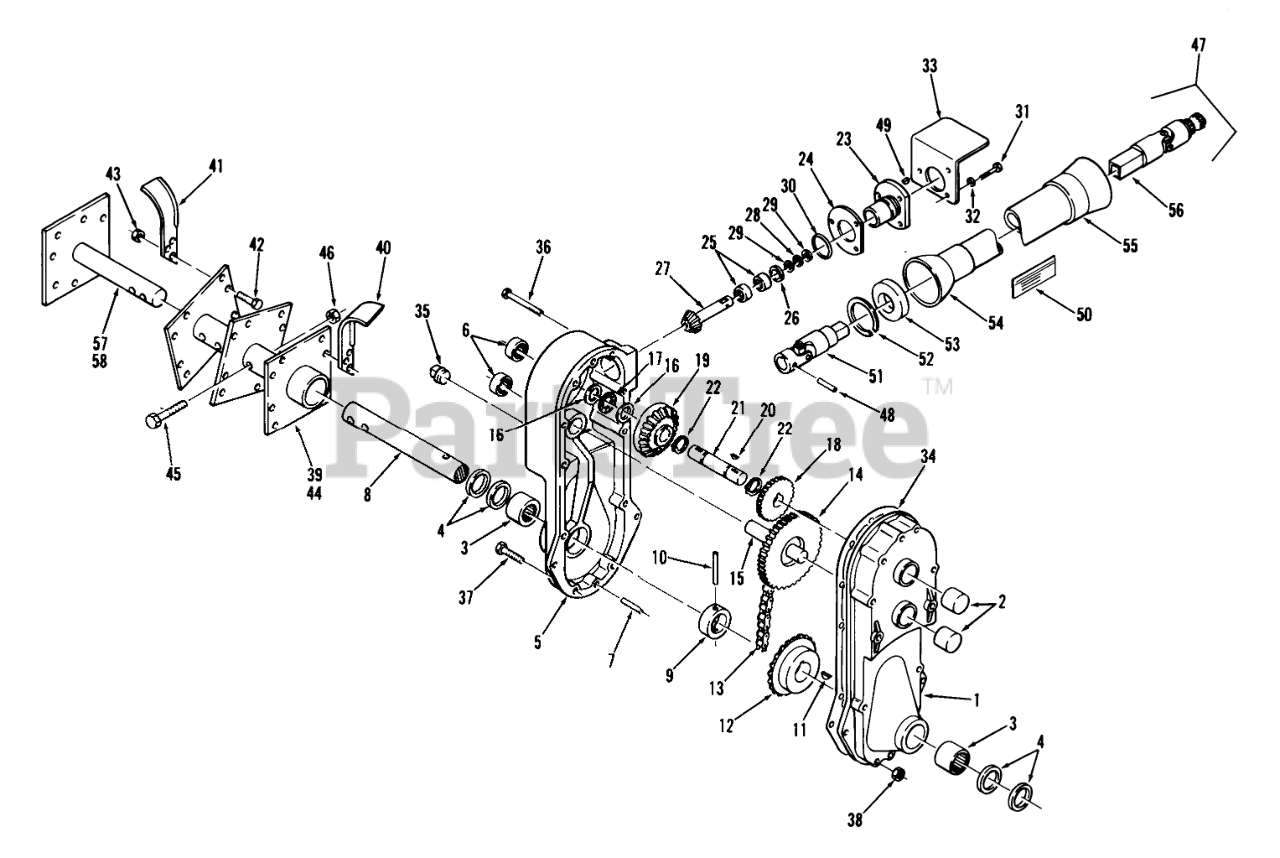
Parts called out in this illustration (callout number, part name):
1	Case-R.H.
2	BEARING-NEEDLE 1X1
3	Needle Bearing 11/2 x 1
4	SEAL-OIL
5	Case-L.H.
6	BEARING-NEEDLE
7	ROLL PIN 3/8 X 1
8	Tine Shaft 1 1/2 Dia.
9	Spacer
10	Spirol Pin 5/16 x 2 1/2
11	Key #129 Woodruff
12	Sprocket-20 T-#60
13	Chain #60-3/4 P x 44 P
14	Reduction Gear
15	Shaft 1.00 Dia.
16	WASHER-THRUST
17	BEARING-THRUST
18	GEAR
19	Bevel Gear 40 T
20	KEY-WOODRUFF
21	SHAFT
22	Snap Ring
23	HOUSING-INPUT SHAFT
24	Gasket
25	BEARING-NEEDLE
26	SEAL-OIL
27	Assy. Pinion Gear and Shaft
28	Bearing-Thrust
29	SHIM WASHER
30	O-RING
31	BOLT
32	LOCKWASHER
33	PTO Shield
34	GEAR CASE GASKET
35	SOLID PIPE PLUG
36	H H C S
37	Screw-Hex. Hd.
38	NUT
39	R.H. Tine Shaft Assembly
40	TINE RH R
41	TINE LH
42	7/16-14 x 1 1/4 Bolt
43	Nut
44	L.H. Tine Shaft Assembly
45	Bolt 5/8-11 x 2 3/4
46	E.S. Nut 5/8-11
47	Drive Shaft Assembly
48	SPIROL PIN
49	KEY-WOODRUFF
50	Washer
51	U-Joint with tube
52	Bearing Retainer
53	Bearing
54	ASSY SHIELD
55	Shield-2"
56	U-Joint with shaft
57	R.H. Tine Shaft Assembly
58	L.H. Tine Shaft Assembly
